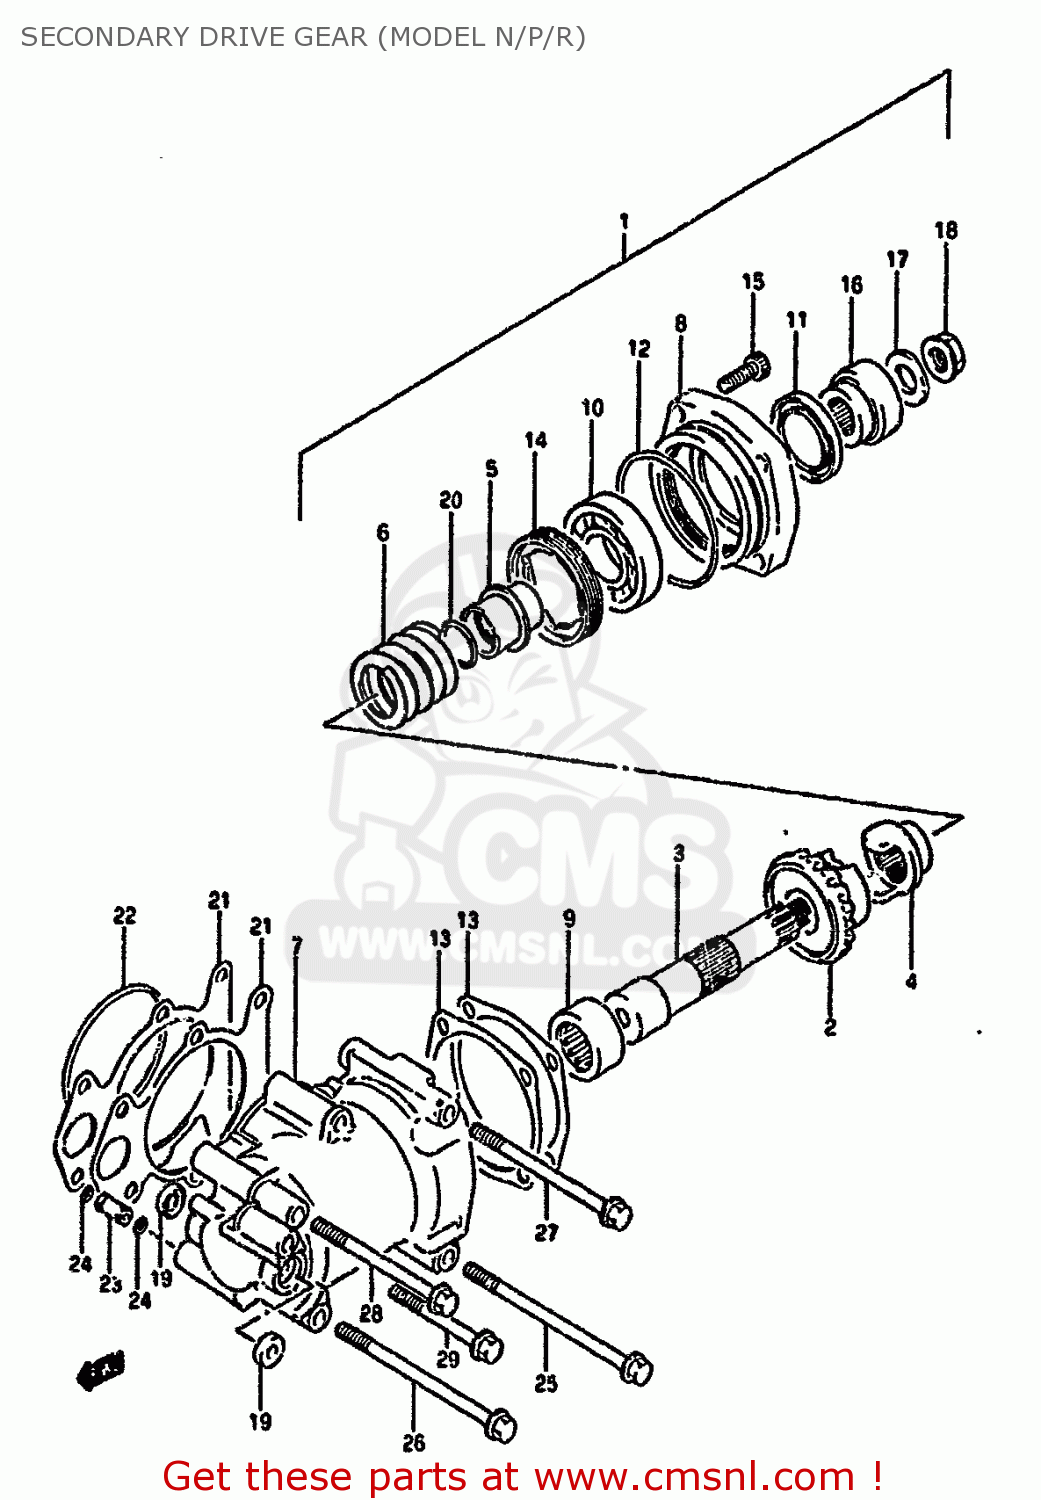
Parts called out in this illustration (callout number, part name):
1	GEAR & CASE SET,SEC BEVEL
2	GEAR,SECONDARY DRIVEN
3	SHAFT,SECONDARY DRIVEN BEVEL
4	DOG,OUTPUT CAM
5	STOPPER,CAM SPRING
6	SPRING
7	CASE
8	HOUSING,SECONDARY DRIVEN BEARING
9	BEARING(32X48X22)
10	BEARING(28X68X18)
11	SEAL,OIL(38X54X6)
12	O RING(D:3.7,ID:76.5)
13	SHIM,SECONDARY DRIVEN
14	STOPPER,SEC DRIVEN BEARING
15	BOLT
16	COUPLING,SECONDARY DRIVEN BELT
17	WASHER(16.5X36X4)
18	NUT
19	SEAL,OIL(6X18X5)
20	O RING(D:2,ID:21.9)
21	SHIM,SECONDARY DRIVE NO.1
22	O RING(D:2.2,ID:88)
23	PIPE,SECONDARY CASE OIL
24	O RING(D:1.7,ID:6)
25	BOLT(8X125)
26	BOLT(8X120)
27	BOLT(8X105)
28	BOLT
29	BOLT
